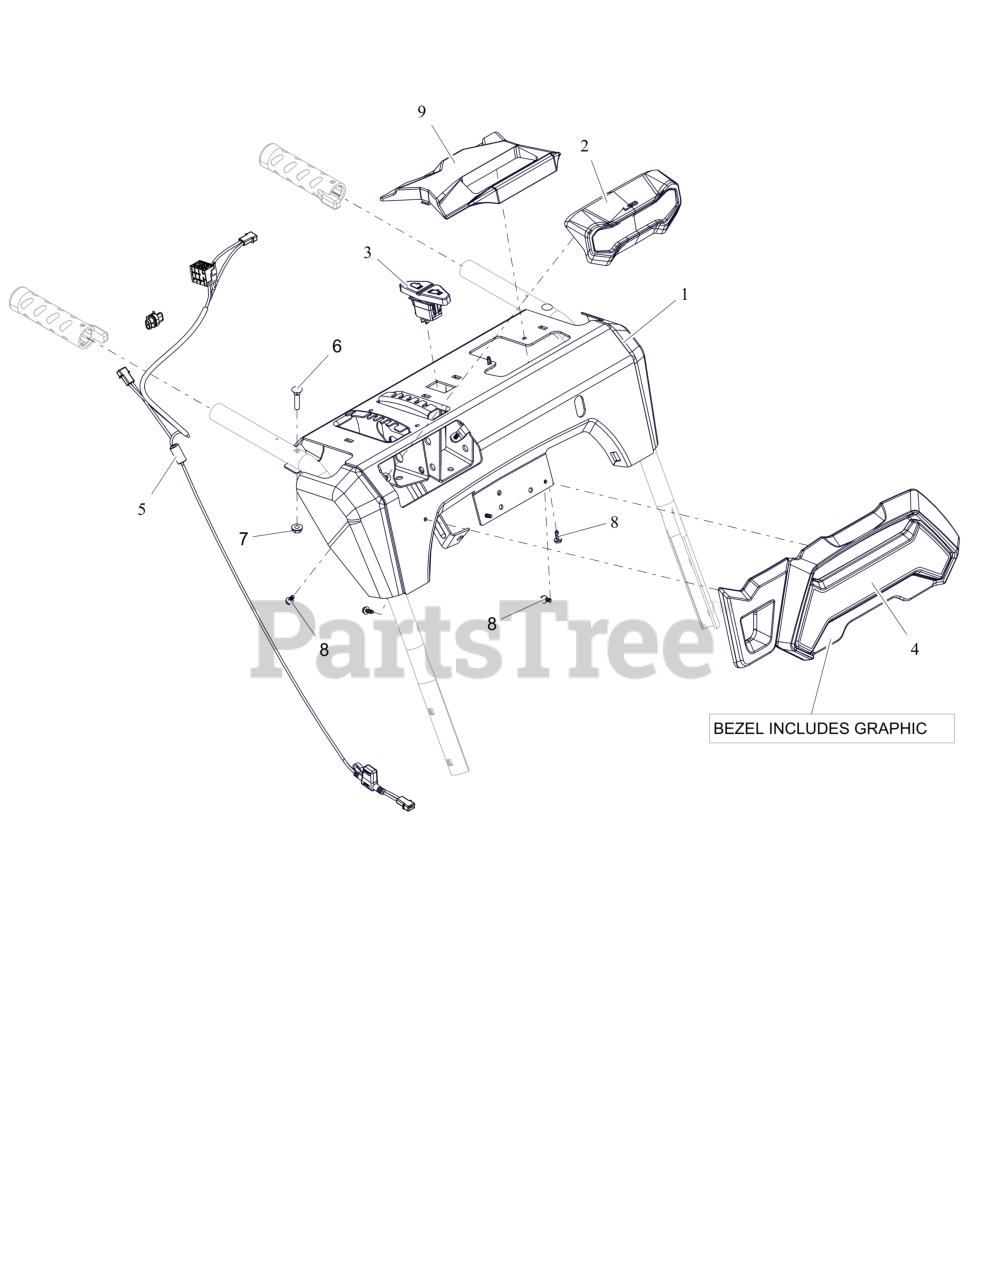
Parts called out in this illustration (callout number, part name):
1	PANEL, CONTROL-EFI ID W/DECAL
2	HEADLIGHT ASM- LED
3	SWITCH- ROCKER SPST-ON/OFF
4	BEZEL- LARGE - PLATINUM
5	HARNESS- WIRE - LT HG
6	BLT-RDHDXLSQNK.25-20X1.25 G5ZC
7	NUT-LK-CTR-FLG .25-20 ZC120
8	SCR, PLASTIC #10X.50
9	BEZEL- OPERATOR - QT
